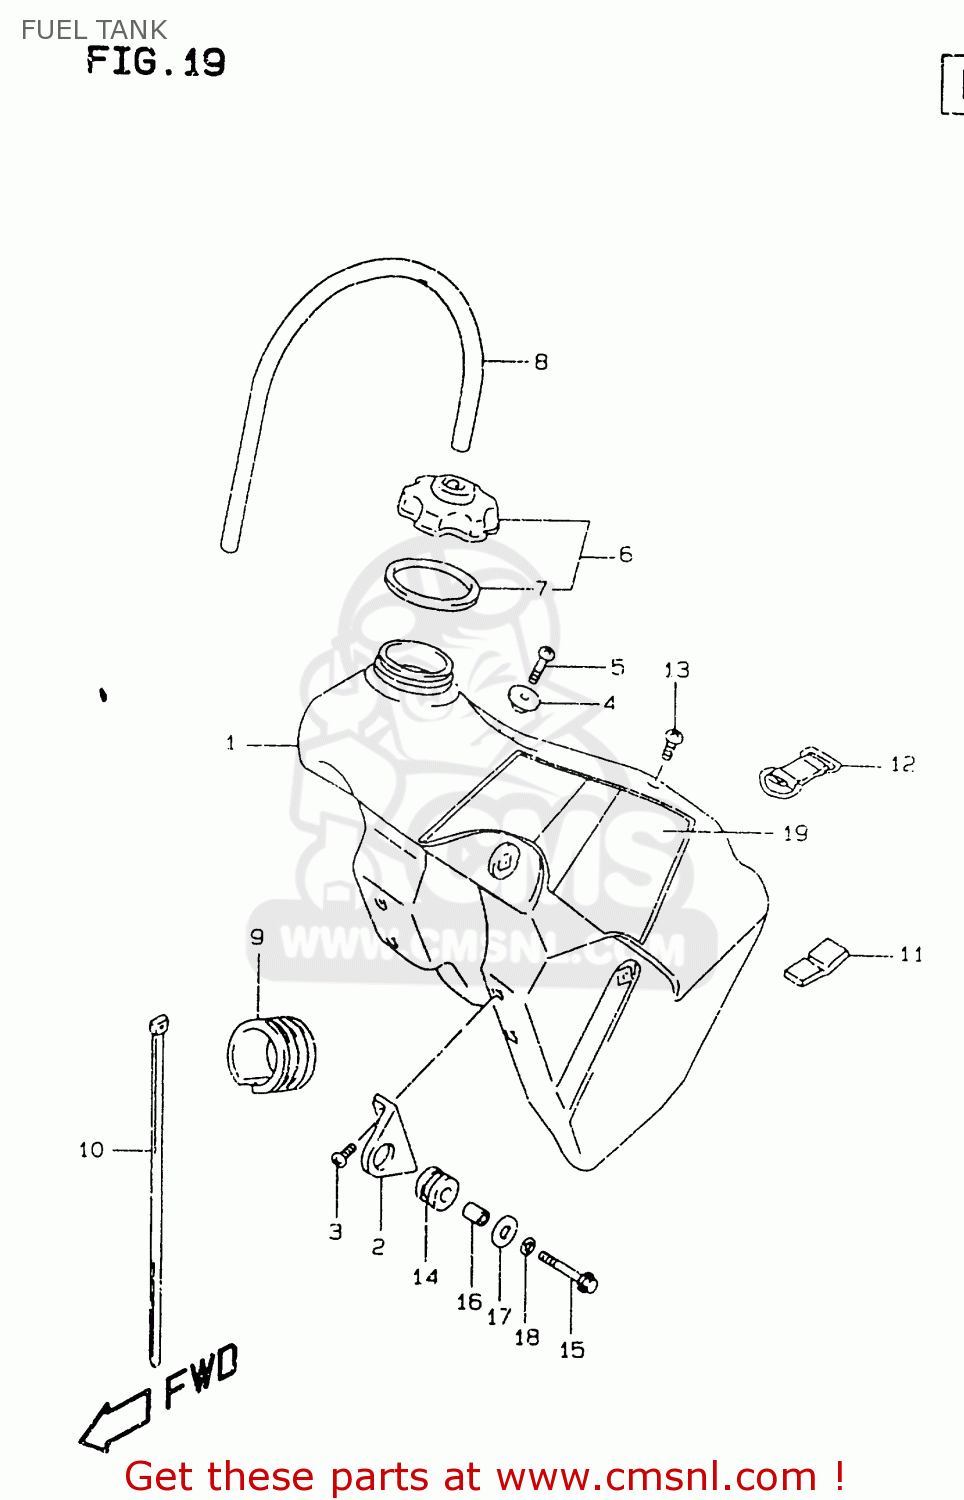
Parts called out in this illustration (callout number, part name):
1	TANK,FUEL(YELLOW)
2	BRACKET,FUEL TANK FR
3	SCREW
4	HOOK,SEAT FR
5	SCREW
6	CAP SET,FUEL TANK
7	GASKET,CAP (NAS)
8	HOSE (5.3X10.5X600)
9	CUSHION,FUEL TANK NO.1
10	CLAMP(L:300)
11	CUSHION
12	BAND,FUEL TANK RR
13	SCREW
14	CUSHION,MUFFLER
15	BOLT,G/S SWITC
16	SPACER(6.5X9X13.5)
17	WASHER(6.5X24X1.2)
18	LOCK WASHER
19	TAPE SET,FUEL TANK
